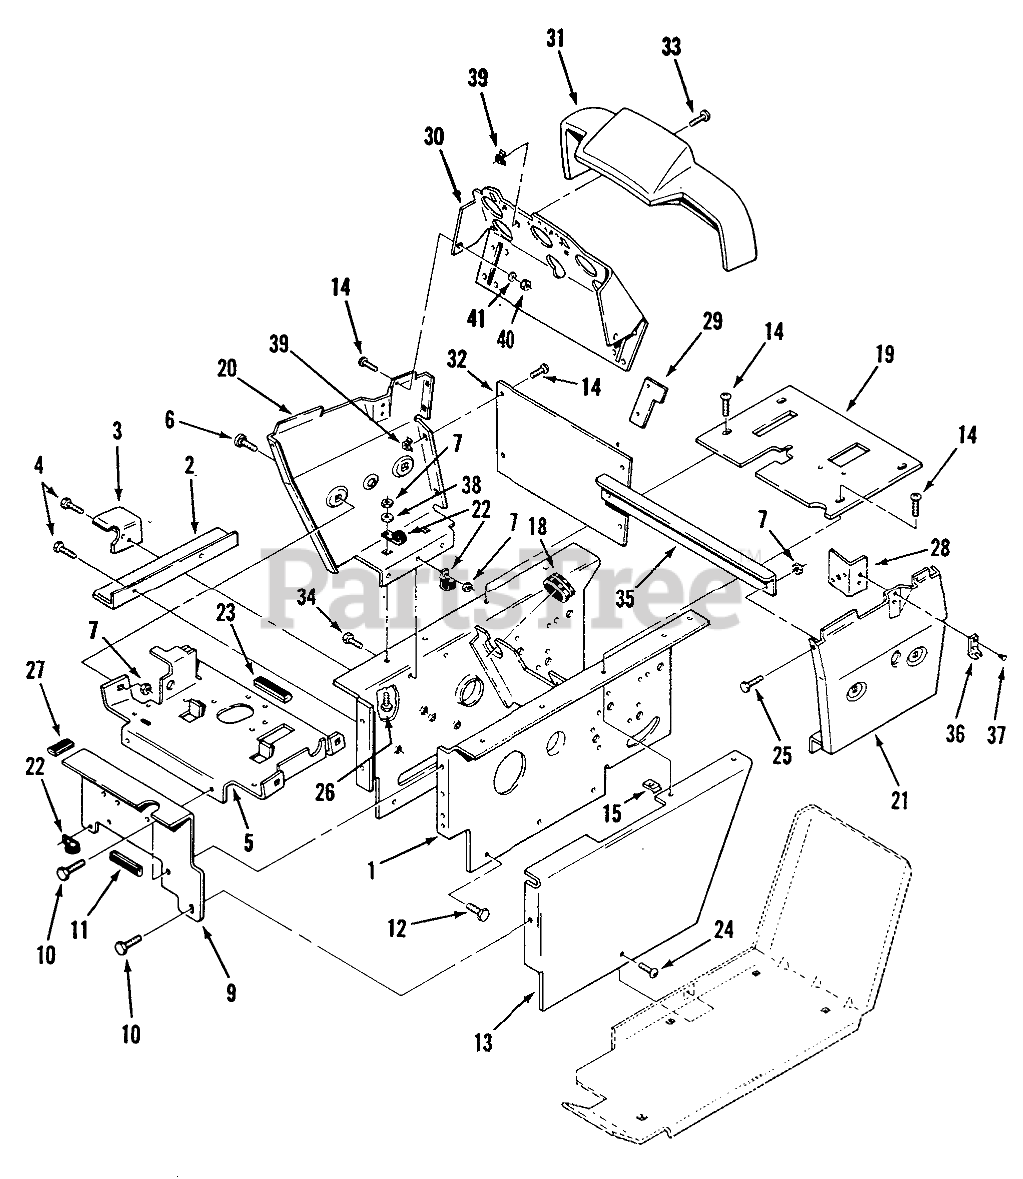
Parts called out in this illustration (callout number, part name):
1	Hoodstand
2	ANGLE-BELT GUARD B
3	BRCKET-BLT SUTB
4	SCREW
5	SUPPORT-BATTERY B
6	Bolt
7	Nut
9	PLATE-FRT HOODSTA B
10	SCREW
11	EDGE TRIM 2" 102896
12	SCREW
13	COVER-L.H. R
14	SCREW-PPH
18	GROMMET
19	PLATE-SHIFT B (NS)
20	Panel-RH
21	PANEL-SIDE LS B
22	CLIP
23	DECAL-TACHAMATIC
24	Screw
24	WASHER 5/16 SAE
25	H H C S
26	CARRIAGE BOLT -4
27	DECAL-TACHAMATIC
28	BRACKET-SWITCH SU
29	STOP-CHOKE
30	PANEL ASSY B
32	Plate-Hoodstand
33	SCREW 1/4-20X.87
34	Bolt
35	STIFFENER-PANEL B
36	Latch Keeper (included in 106825 Hood Latch)
37	RIVET
38	WASHER 5/16 SAE
39	Nut 1/4-20
40	Nut
